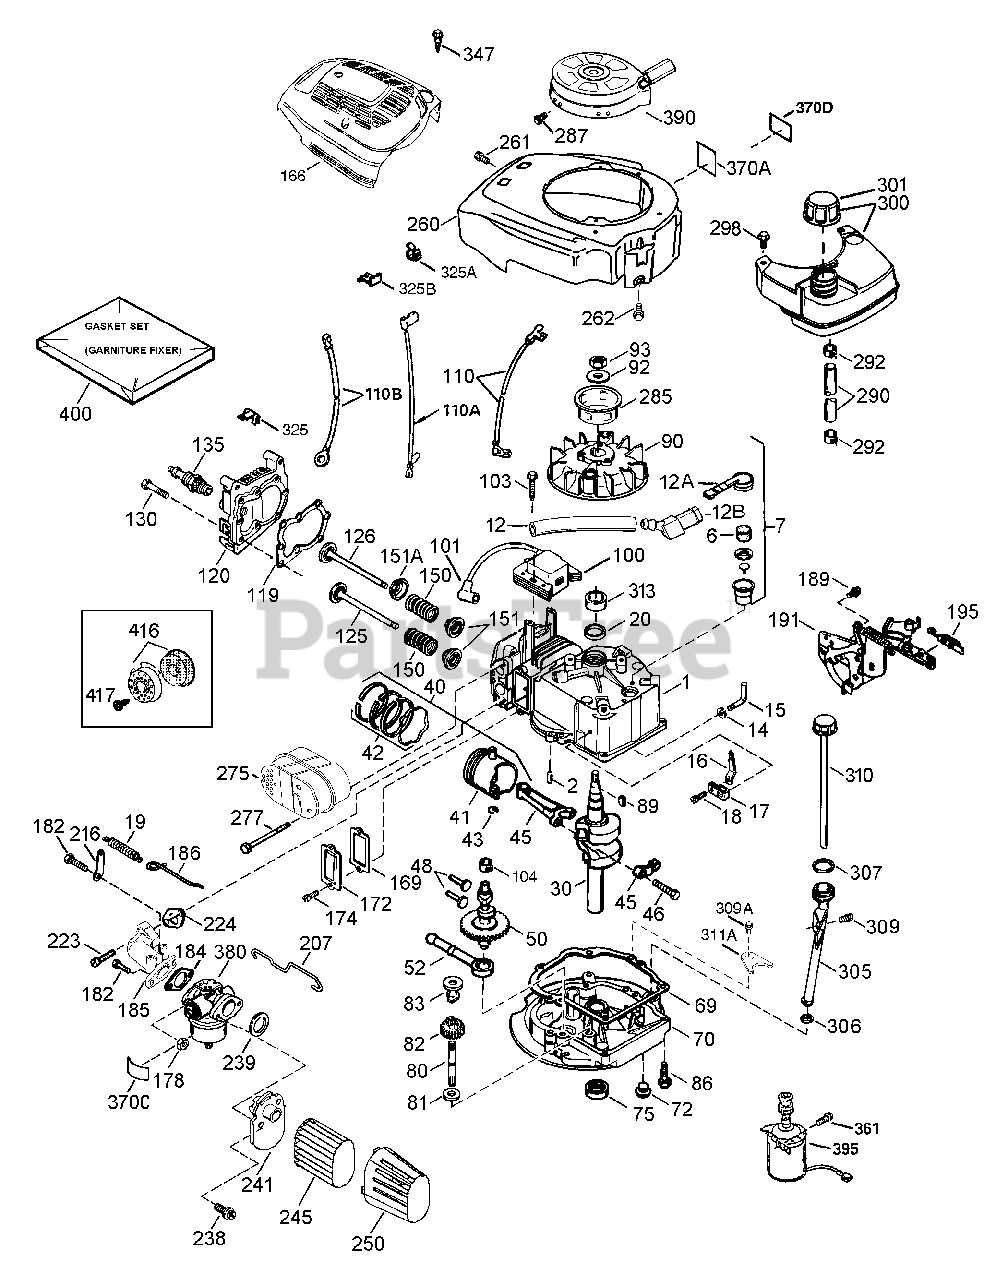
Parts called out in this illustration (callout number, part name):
300	Fuel Tank (Incl. REF. #292 and 301)
301	Fuel Cap ASM
305	Tube-Oil Fill
306	INOIN-Ring
307	INOIN-Ring
309	Screw, 10-32 x 1/2in
309A	Screw, 10-24 x 3/4in
310	Dipstick
311A	Bracket-Hold Down
313	Spacer
325	Wire Clip
325A	Wire Clip
325B	Wire Clip
347	Screw, 10-32 x 27/32in
361	Screw, 1/4-20 x 1/2in
370A	Decal-Lubrication
370C	Decal-Primer
370D	Decal-Warning
380	Carburetor (Incl. REF. #184)
390	Starter-Rewind
395	Starter-Electric 12 Volt
400	Gasket Set (Incl. Items Marked PK in Notes)
416	Spark Arrestor Kit (Optional)
417	Screw, 8-32 x 3/8in
